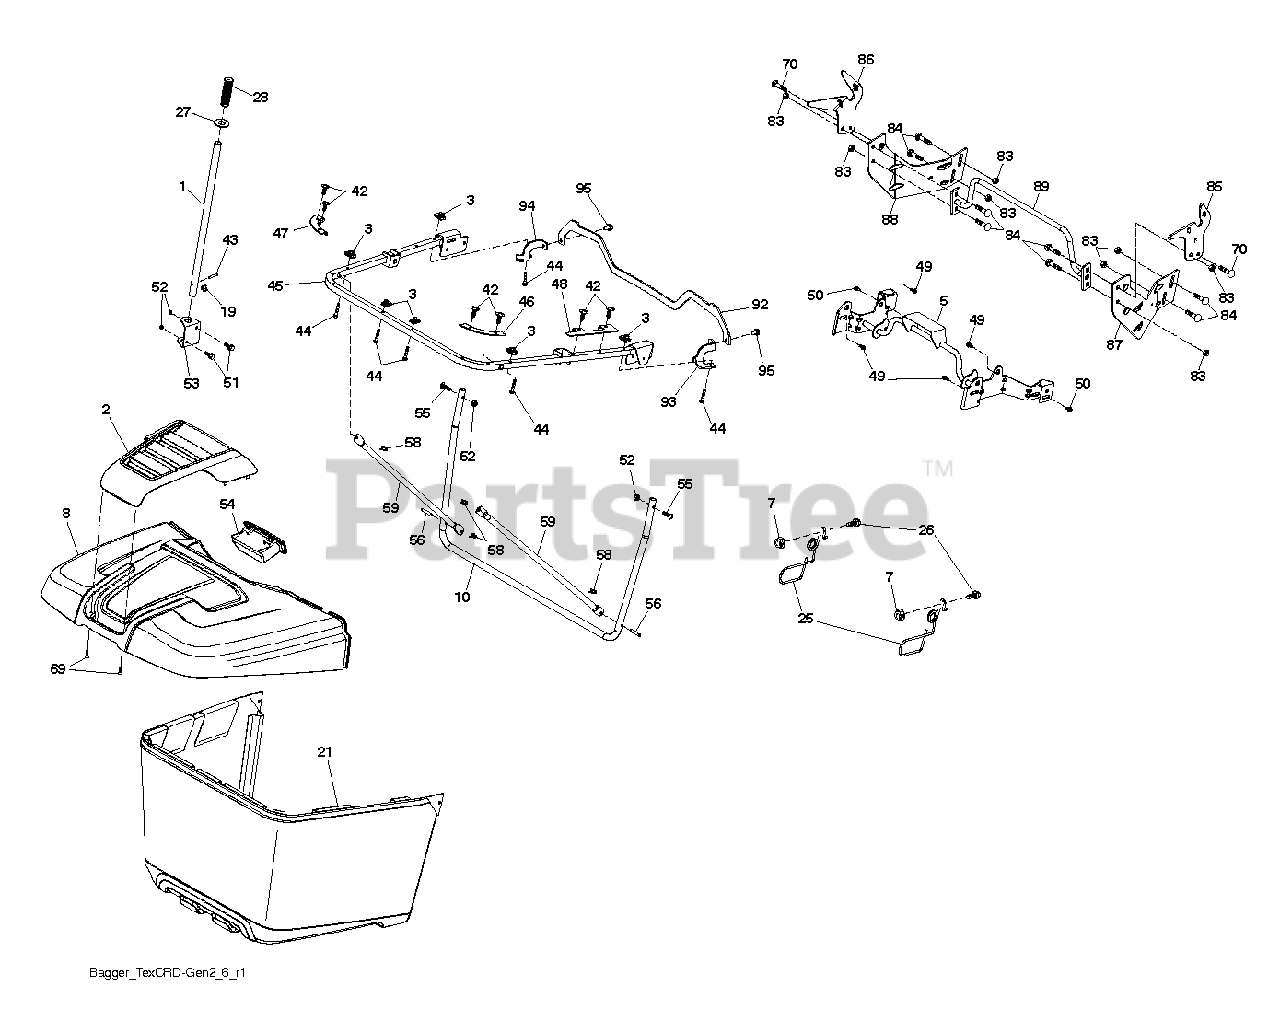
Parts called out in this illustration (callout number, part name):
1	TUBE.HANDLE.BAGGER.CRD/SRD.BLA
2	APPLIQUE.BAGGER
3	1/4-20 U NUT
5	FRAME TEX_CRD_GEN2 UPPER PIVOT
7	NUT T
8	BAGGER TOP
10	FRAME TEX_CRD_GEN2 BAGGER FRAM
19	PIN.COTTER.5/16.BOW TI
21	BAG FRAME BAGGER ASSEMBLY. HUS
25	LATCH LATCH. BAG. CRD GEN 2
26	SCREW HEX CRT
27	GROMMET RUBBER GROMMET, DUMP T
28	GRIP.HANDLE.BLACK
42	CLIP CHRISTMAS TREE CLIP
43	RIVET,DRILLED
45	FRAME TEX_CRD_GEN2 UPPER U FRA
46	CONNECTOR RIGHT BAGGER CORNER
47	CONNECTOR LEFT BAGGER CORNER C
48	BAFFLE BAGGER SIDE CLOSE-OUT
49	BOLT, SHOULDER 5/16-18
50	BOLT, 5/16-18 X 1 3/4
51	BOLT.CARR.SQNK.5/16-18UNC.X3/4
52	NUT.71038.31-18.HEX.NYLOCK
53	BRACKET DUMP HANDLE BRACKET, T
54	HANDLE BAGGER TOP FRONT HANDLE
55	BOLT
56	PIN.CLEVIS.183
58	RETAINER CLIP PM
59	TUBE BAGGER SPREADER TUBE, TEX
69	SCREW,#8.FLAT.HEAD.DRILL.TIP
70	SCREW, 3/8-16X3/4
83	NUT
84	BOLT D
85	BRACKET.RH.PIVOT.MAN.DUMP.BLAC
86	BRACKET.LH.PIVOT.MAN.DUMP.BLAC
87	BRACKET.RH.MID.SUP.BAG.TEX.CRD
88	BRACKET.LH.MID.SUP.BAG.TEX.CRD
89	TUBE.WELD.OFSET.STRUT.BAG.X431
92	BRACKET.PNT.BAGGER.TOP.SUPPORT
93	BRACKET.PNT.RH.SUPPORT.ATTACH
94	BRACKET.PNT.LH.SUPPORT.ATTACH
95	SCREW
